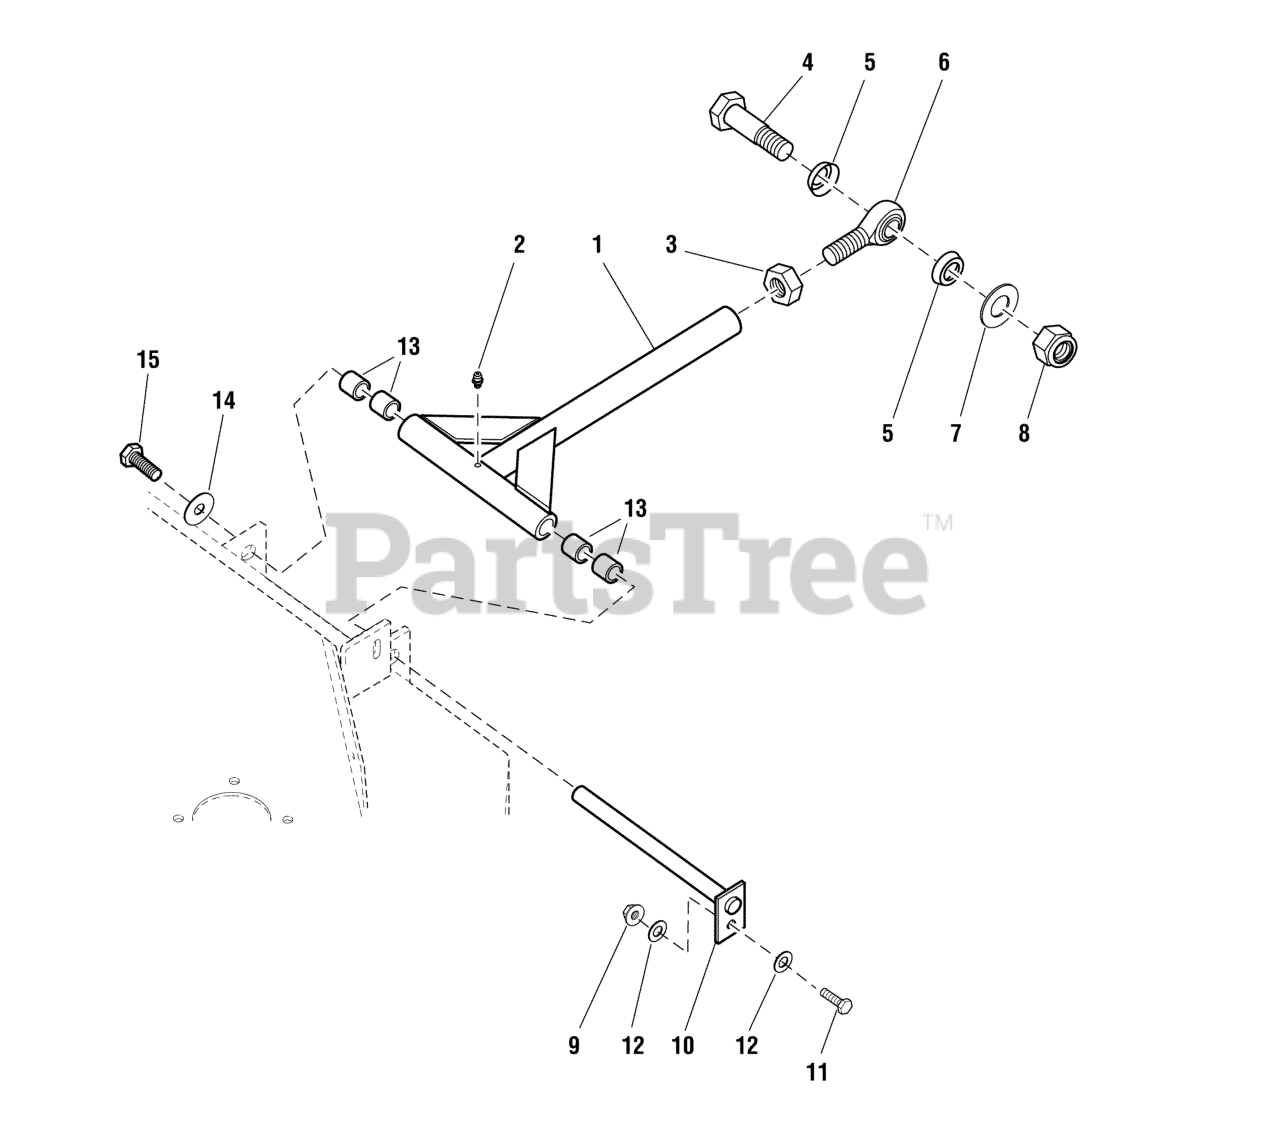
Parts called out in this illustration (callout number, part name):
1	ASSM, DECK PUSHER BAR
2	GREASE FITTING, 1/4-28 STRAIGHT
3	NUT, 3/4-16 HEX JAM
4	BOLT, 3/4-16 X 3" YZ GD5
5	SEAL, 3/4" ROD END
6	BALL JOINT, 3/4-16 MALE
7	WASHER, 3/4 SAE
8	NUT, 3/4-16 HEX NYLON LOCK
9	NUT, 3/8-16 HEX NYLON LOCK
11	BOLT, 3/8-16 X 1" GD5 CZ
12	WASHER, 3/8 SAE
13	BUSHING, .75 X 1.00 X 1.00, PLASTIC
14	WASHER, .390 X 1.50 X .109 YZ
15	BOLT, 3/8-16 X 1" GD5 CZ
